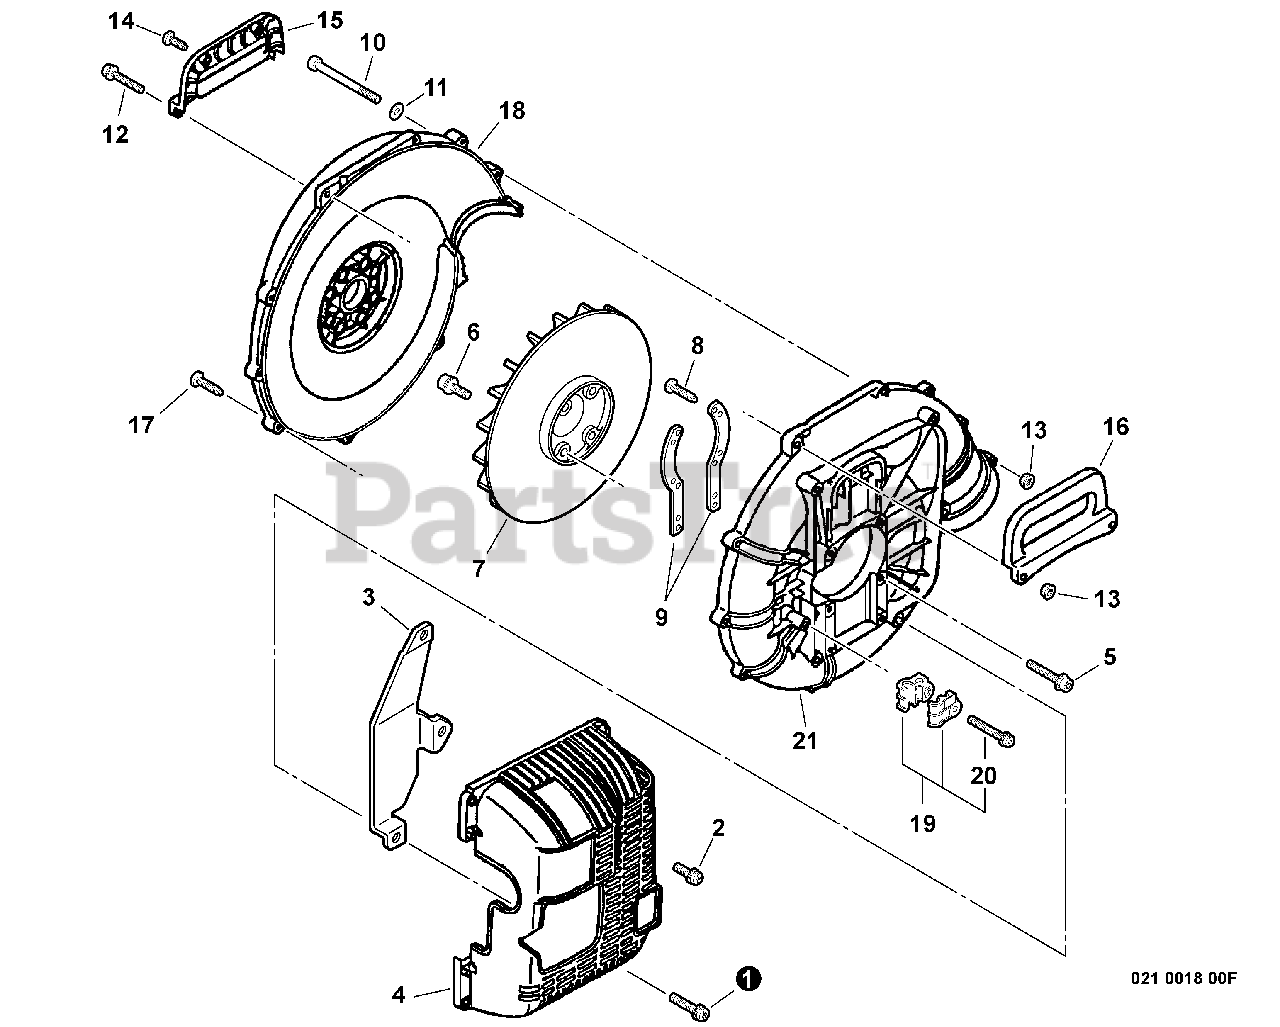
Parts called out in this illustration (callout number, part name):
1	SCREW 5×18
2	SCREW 5×10
3	INSULATOR
4	COVER, ENGINE
5	SCREW 5×32
6	BOLT 5×20
8	SCREW TAPPING 3×12
9	BRACKET, ENGINE
10	BOLT 5×60
11	WASHER 5.3×10×1
12	SCREW 5×45
13	NUT, FLANGE M5
14	SCREW 5×16
15	HANDLE
17	SCREW 5×30
18	COVER, FAN - INNER
19	CABLE HOLDER KIT
20	SCREW 5×25
21	COVER, FAN - OUTER
